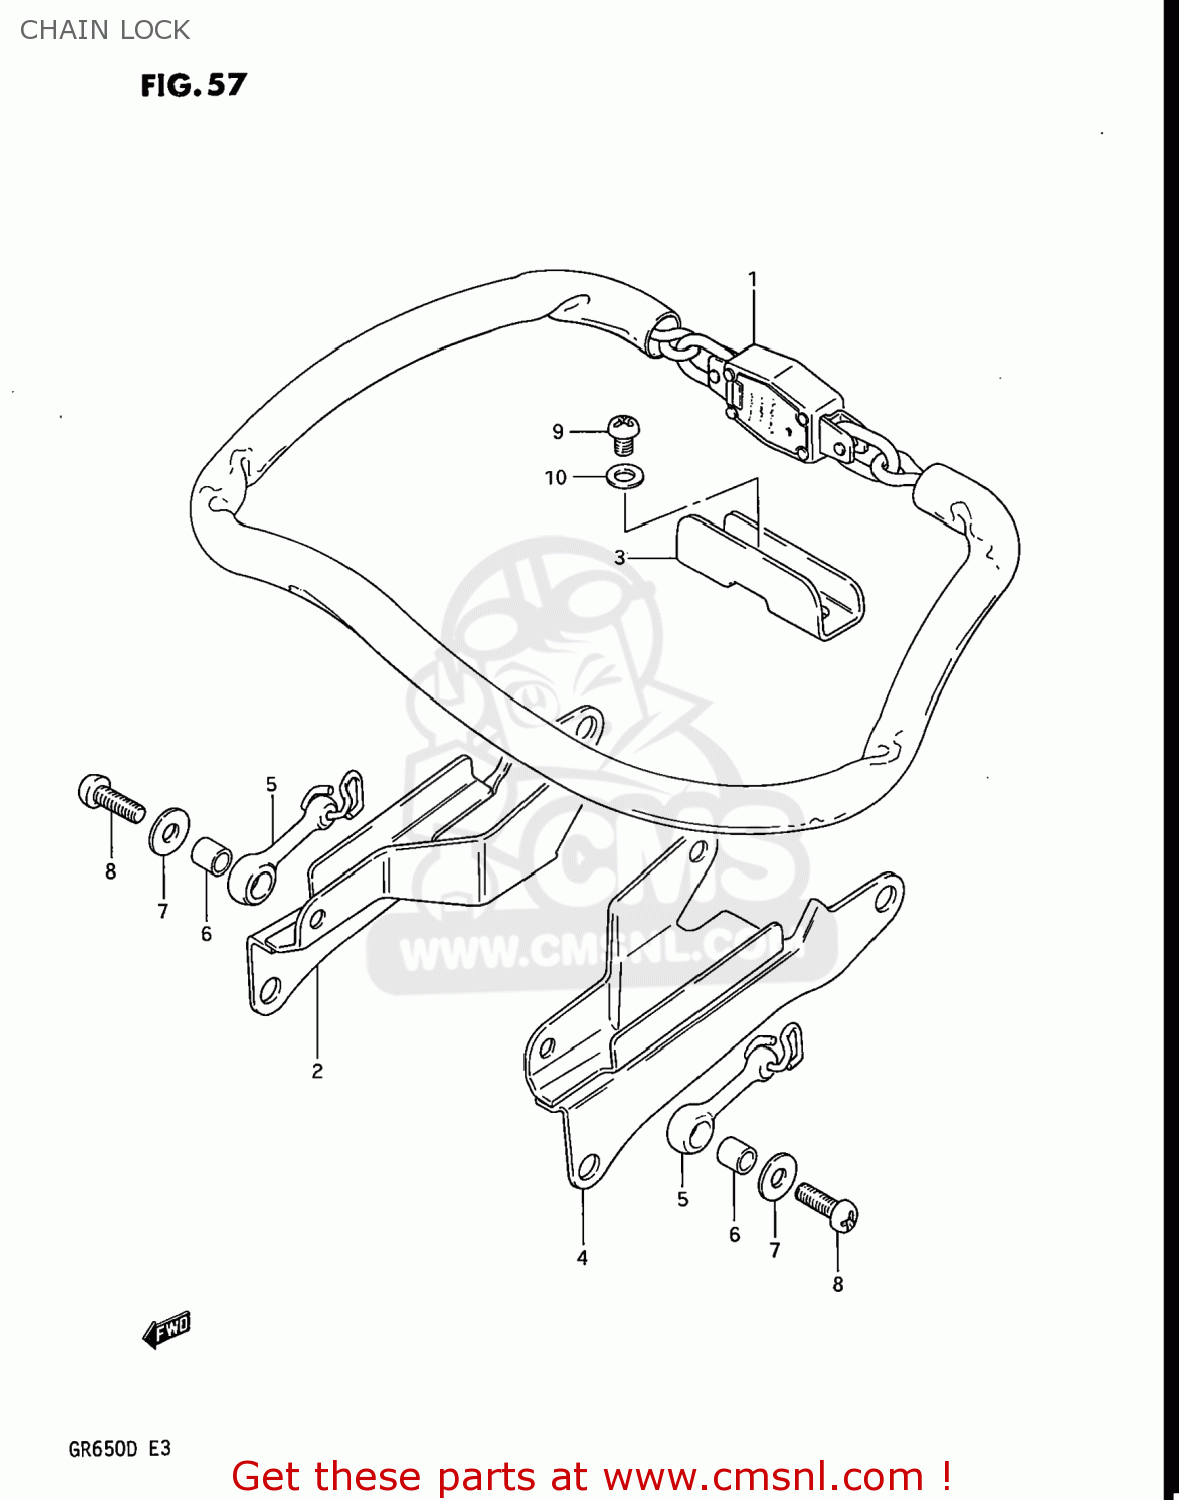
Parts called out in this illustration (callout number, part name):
1	LOCK ASSY, CHAIN
2	HOLDER, RH
3	HOLDER, REAR
4	HOLDER, LH
5	BAND
6	SPACER (6.1X9X9)
7	WASHER
8	SCREW
9	SCREW
10	WASHER
